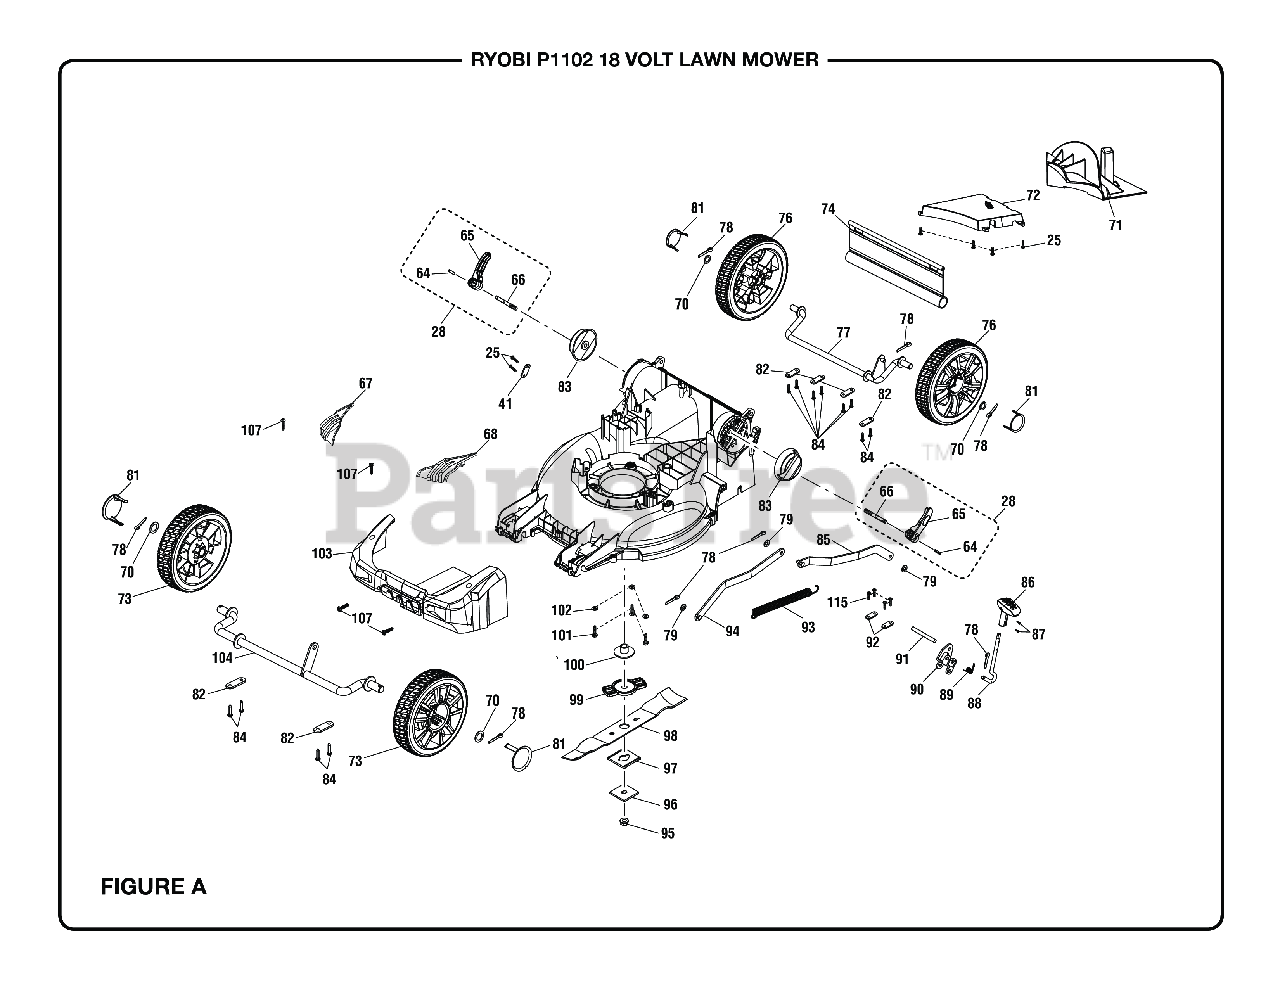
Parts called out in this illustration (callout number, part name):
25	Screw (M4 x 16 mm, T20 Torx Pan Hd.).
28	Handle Lock Assembly
41	Wire Press Plate
64	Spring Pin
65	Adjust Height Handle
66	Quick Lock Press
67	Grass Protector (Right)
68	Grass Protector (Left)
70	Washer (ID13.5 x OD20 x 1t)
71	Mulching Plug
72	Rear Cover
73	Front Wheel w/Bearing & Cap 6 in.
74	Rear Skirt
76	Rear Wheel w/Bearing & Cap 8 in.
77	Rear Wheel Axle
78	Cotter PinÏ? (2.5)
79	Washer (ID8.4 x OD18 x 1t)
81	Wheel Cover
82	Axle Pressure Plate
83	Quick Lock Press Block
84	Screw (M4 x 18 mm, T20 Torx Pan Hd.)
85	Rear Lift Rod
86	Height Adjustment Handle
87	Screw (M3 x 9 mm, Flat Hd.)
89	Torsion Spring (Height Adjustment)
90	Adjustment Height Bracket
91	Axle (Height Adjustment)
92	Pressure Plate (Height Adjustment)
93	Rentention Spring
94	Front Lift Rod
95	Blade Nut (M10 x 1.25, Hex Flange Hd.)
96	Metal Blade Retainer
98	Blade (16 in.)
99	Blade Holder
100	Motor Shaft Bushing
101	Bolt (M6 x 26 mm, Hex Hd.)
102	Washer (ID6.2 x OD15 x 0.08t)
104	Front Wheel Axle
107	Screw (M4 x 20 mm, T20 Torx Pan Hd. S.T.)
115	ST SCREW,STEEL CH M4.0X1.8 PH TORX
